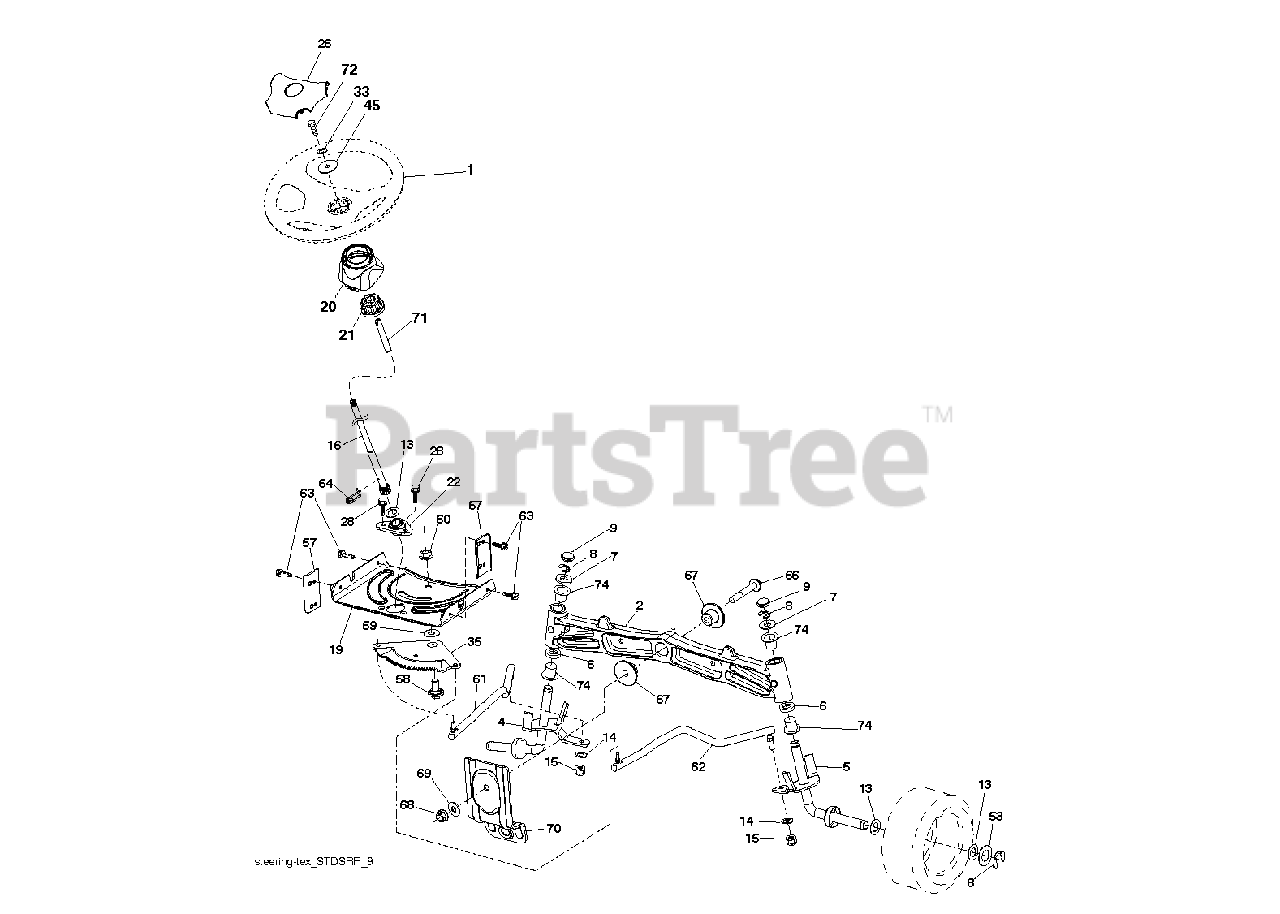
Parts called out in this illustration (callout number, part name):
1	WHEEL.STEERING.STDSRR.BLK/OV
2	AXLE HALF ASM-WELDED
4	SPINDLE.WELDED.LH.15"TEX
5	SPINDLE.WELDED.RH.15"T
8	RING CLIP
9	CAP.SPINDLE
14	WASHER, LOCK 3/8
15	NUT CROWNLOCK 3/8-24
16	SHAFT STEERING
19	PLATE.STEER.DDL.NLT/NG
20	BOOT.STEERING.PREDATOR.LT.BLAC
21	ADAPTER, WHEEL STNG..
22	BUSHING.ASM.STEERING.A
26	CAP.WHL.STRNG.STDSRRD.SRS.BLK
28	SCREW, 3/8-16X3/4
33	LOCKWASHER
35	GEAR.SECTOR.PLATE.DDL.
45	WASHER.11/32
53	WASHER.HARDENED
57	BRACKET.UPSTOP.TEX
58	BOLT.SHOULDER.SECTOR.P
59	WASHER.THURST.SECTOR.S
60	NUT FLANGE LOCK 5/8-11
61	DRAGLINK.LH.BALLSTUD.D
62	DRAGLINK.RH.BALLSTUD.D
63	SCREW
64	RETAINER.CLIP.SPRING.S
66	BOLT HEX FGHD 7/16-14 X 3 SERR
67	BUSHING.PM.FRONT AXLE
68	NUT.LOCK.FLANGE.7/16
69	WASHER.1.5X.505X.118
70	BRKT.DECK.SUSPENSION.F
71	SHAFT EXTENSION STEERING
72	BOLT YT
74	BRNG T
